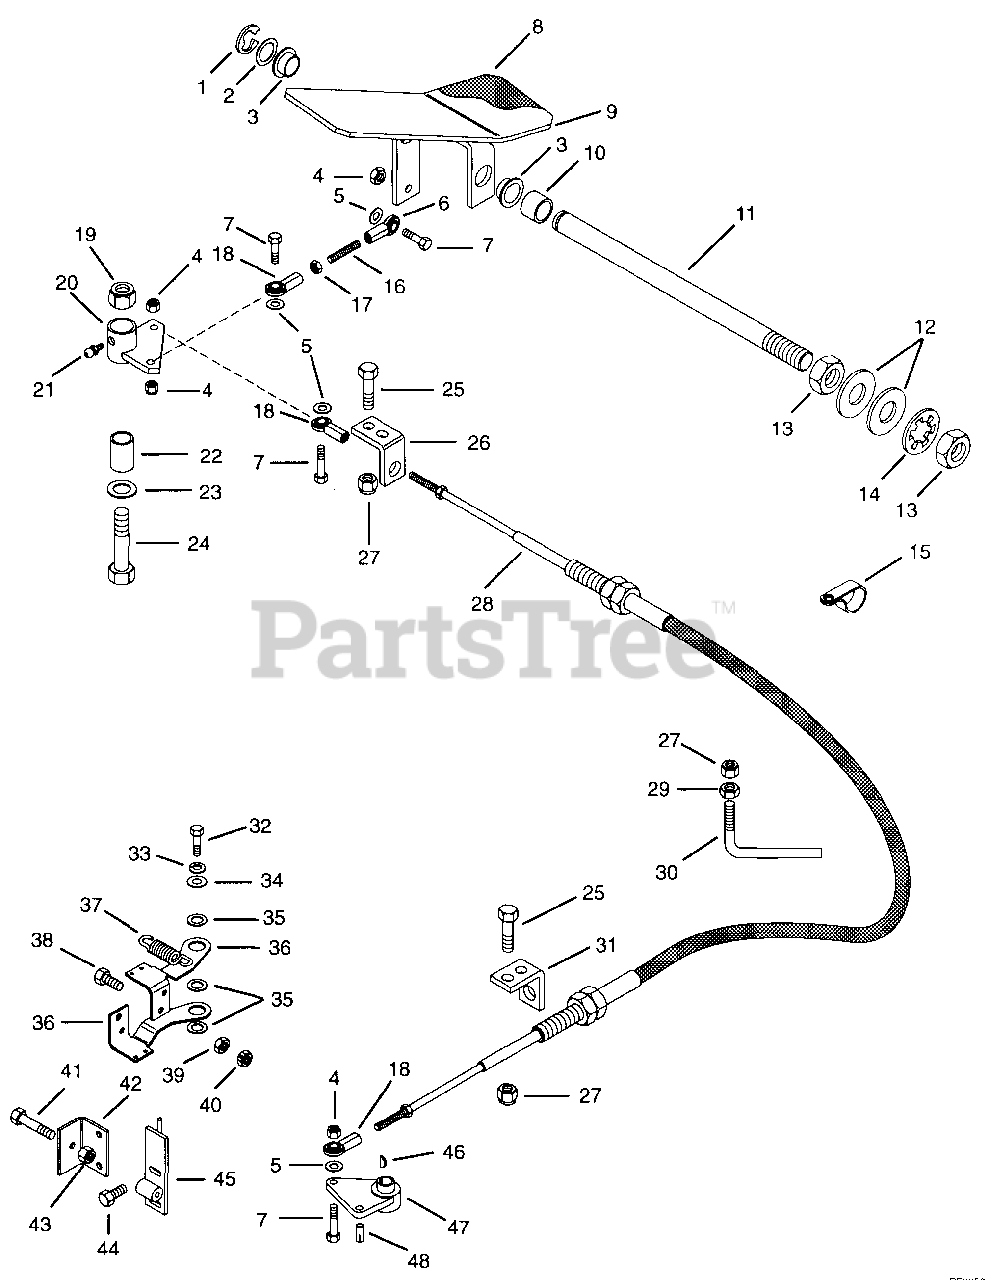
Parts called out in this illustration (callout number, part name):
1	Ring-Retaining-External .574 x .050
2	Bearing-Needle-Thrust .752 x 1.24 x .031
3	Bushing-Flange .762 x 1.0 x .580 x 1.48
4	Nut-Locking-Nylon .250-20
5	Washer-Flat-Steel .281 x .620 x .065
6	Rod End Left Hand
7	Bolt-Hex .25-20 x 1.25 Grade 5
8	Cover, Pedal
9	Weldment, Pedal
10	Bushing, Sleeve .782 x 1.00 x .710
11	Shaft, Pedal
12	Washer-Flat .812 x 1.469 x .134
13	Nut-Jam .75-16
14	Washer-Lock Internal .750
15	Clamp, Cushioned Steel
16	Rod
17	Nut-Jam-Hex .250-28
18	Rod End, Female 1/4-28
19	Nut-Locking-Nylon .50-13
20	Weldment, Lever
21	Fitting-Lube .25-28 x .256
22	Spacer, .562 x .855 x 1.56
23	Washer-Flat-Steel .500 x 1.250 x .083
24	Bolt-Hex .50-13 x 2.50 Grade 5
25	Bolt-Hex .38-16 x 1.00 Grade 5
26	Bracket, Cable
27	Nut-Locking-Nylon .375-16
28	Cable, Forward-Reverse
29	Nut-Jam .375-16
30	Rod, Cable Guide
31	Bracket, Cable
32	Bolt-Hex .25-20 x 1.50 Grade 5
33	Washer-Lock .250
34	Washer-Flat-Steel .281 x 1.250 x .062
35	Washer-Flat-Steel .760 x 1.125 x .030
36	Lever, Neutral
37	Spring-Tension .075 x .75 x 2.25
38	Bolt-Hex .31-24 x .75 Grade 5
39	Nut-Jam .312-24
40	Nut-Locking-Center .312-24
41	Bolt-Hex .31-18 x 1.25
42	Bracket
43	Nut-Locking-Nylon .312-18
44	Screw-Tapping .313-18 x .875
45	Weldment, Neutral Stop
46	Key, Woodruff .13 x .50
47	Arm, Transmission Control
48	Pin-Groove .250 x .75
